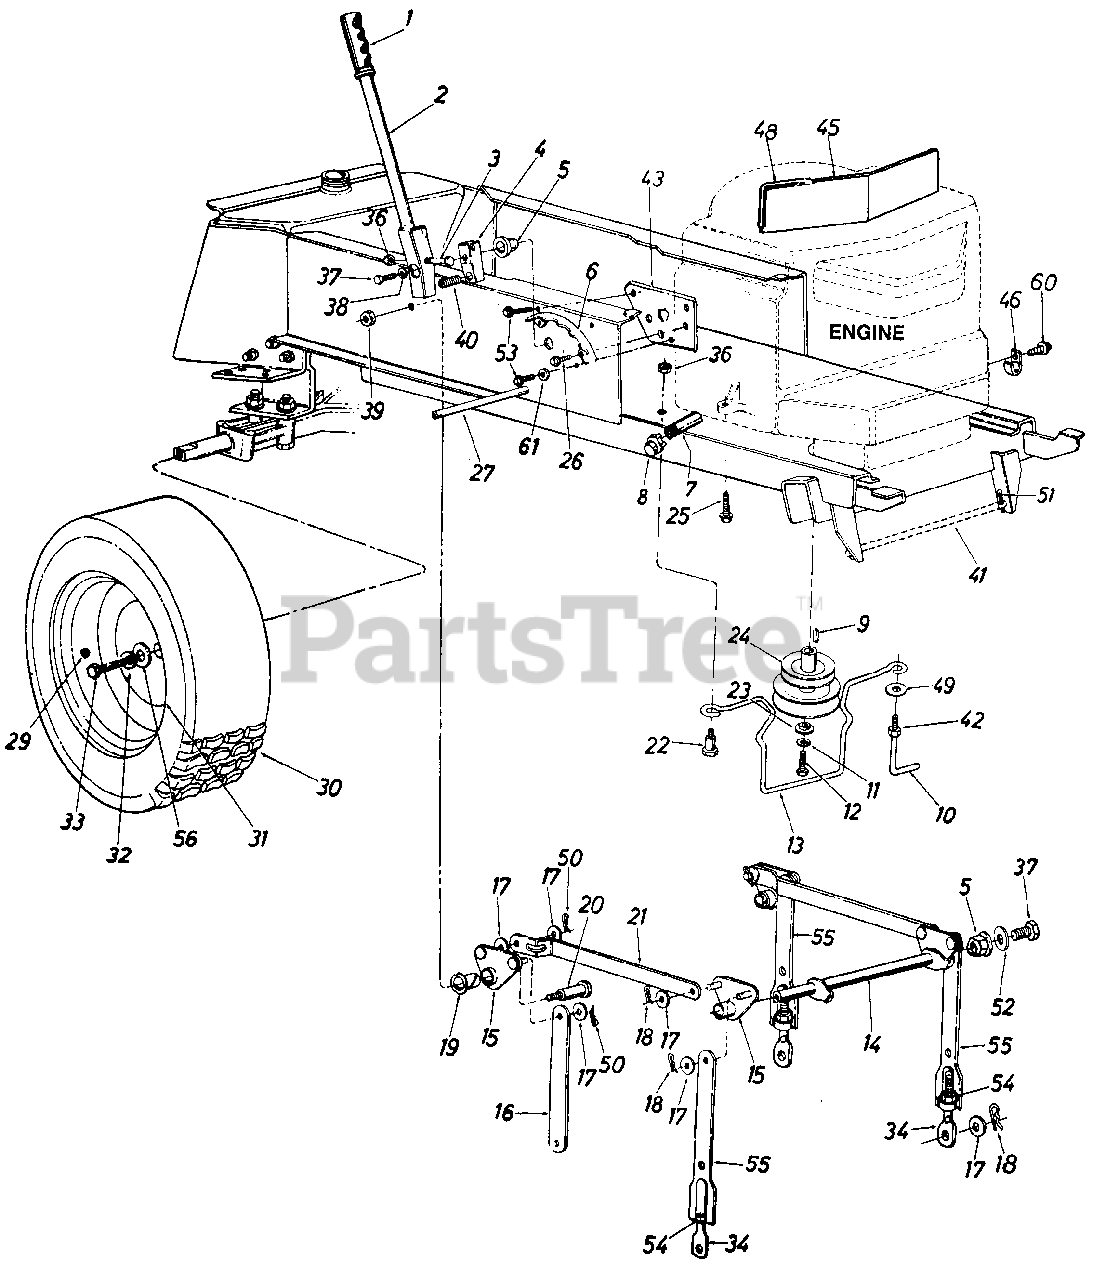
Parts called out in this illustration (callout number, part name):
1	Grip
2	Lift Handle Ass'y.
3	Hex Scr. 5/16-18 x 1.50" Lg.
4	Lift Shaft Drive
5	Plastic Hex Brg. 518" I.D.
8	Pipe Cap 3/8-18 Npt.
9	Sq. Key 1/4" x 1.50" Lg.
10	Belt Guard Lock Pin
11	L-Wash. 7/16" Scr.
12	Hex Scr. 7/16-20 x 1.50" Lg.
13	Belt Guard
14	Lift Shaft Ass'y.
15	Lift Pivot Brkt. Ass'y.
17	Fl-Wash. 112" I.D. x 1.00" O.D. x .090
18	Hairpin Cotter
19	Nyliner 5/8" I.D. x .88" Lg.
20	Shld. Scr. 5/8" Dia. x .96" Lg. 3/8-16
23	Flat Wash. .44" I.D. x 1.25" O.D. x .17
24	Two-Step Engine Pulley
25	Hex Wash. Hd. Scr. 3/8-16 x 1.25" Lg.
26	Hex Thd. Rolling Scr. 5/16-18 x .75" Lg.
27	Running Board Rod
29	Air Valve
30	Rear Wheel Ass'y. Comp.
31	Rear Wheel Rim Only
32	Bell-Wash. .345" I.D. x .88" O.D.
33	Hex Bolt 5/16-24 x .75" Lg.
34	Eye Bolt Adj. Link 1/2-13 Thd.
36	Hex Cent. L-Nut 5/16-18 Thd.
37	Hex Scr. 5/16-24 x .62" Lg.
38	L-Wash. 5/16" I.D.
39	Hex Center L-Jam Nut 3/8-16 Thd.
40	Compression Spring
41	Deck Connecting Rod
42	Hex Nut 5/16-24 Thd.
46	Mounting Clamp
48	Heat Baffle Seal
49	Bell-Wash. .39" I.D.
50	Cotter Pin .09 Dia. x 1.0" Lg.
51	Int. Cotter Pin
52	Flat Wash. .34" I.D. x 1.12" O.D. x .125
53	Hex Wash. Hd. AB-Tap Scr. 5/16 x .5" Lg.
54	Hex Nut 1/2-13 Thd.
56	Fl-Wash. .34" I.D. x 2.0" O.D.
60	Hex Hd. TT-Tap Scr. 1/4-20 x .5" Lg.
61	Fl-Wash. .34" I.D. x .62" O.D.
